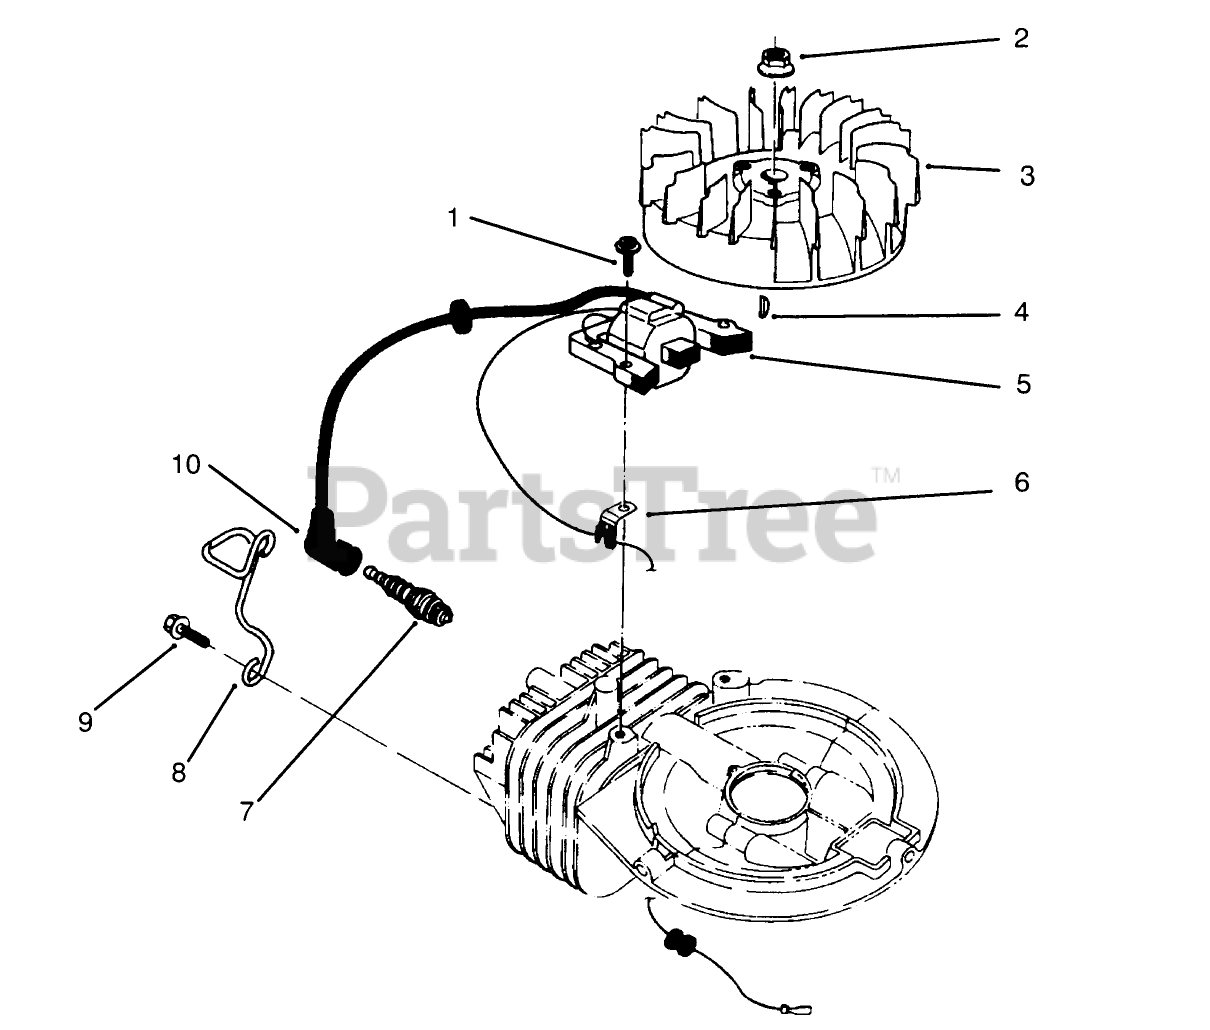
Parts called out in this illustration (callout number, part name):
1	SCREW
3	FLYWHEEL
5	COIL-MAGNETO
6	CLAMP
7	SPARK PLUG
8	PROTECTOR-PLUG
9	SCREW
10	CAP-SPARKPLUG
